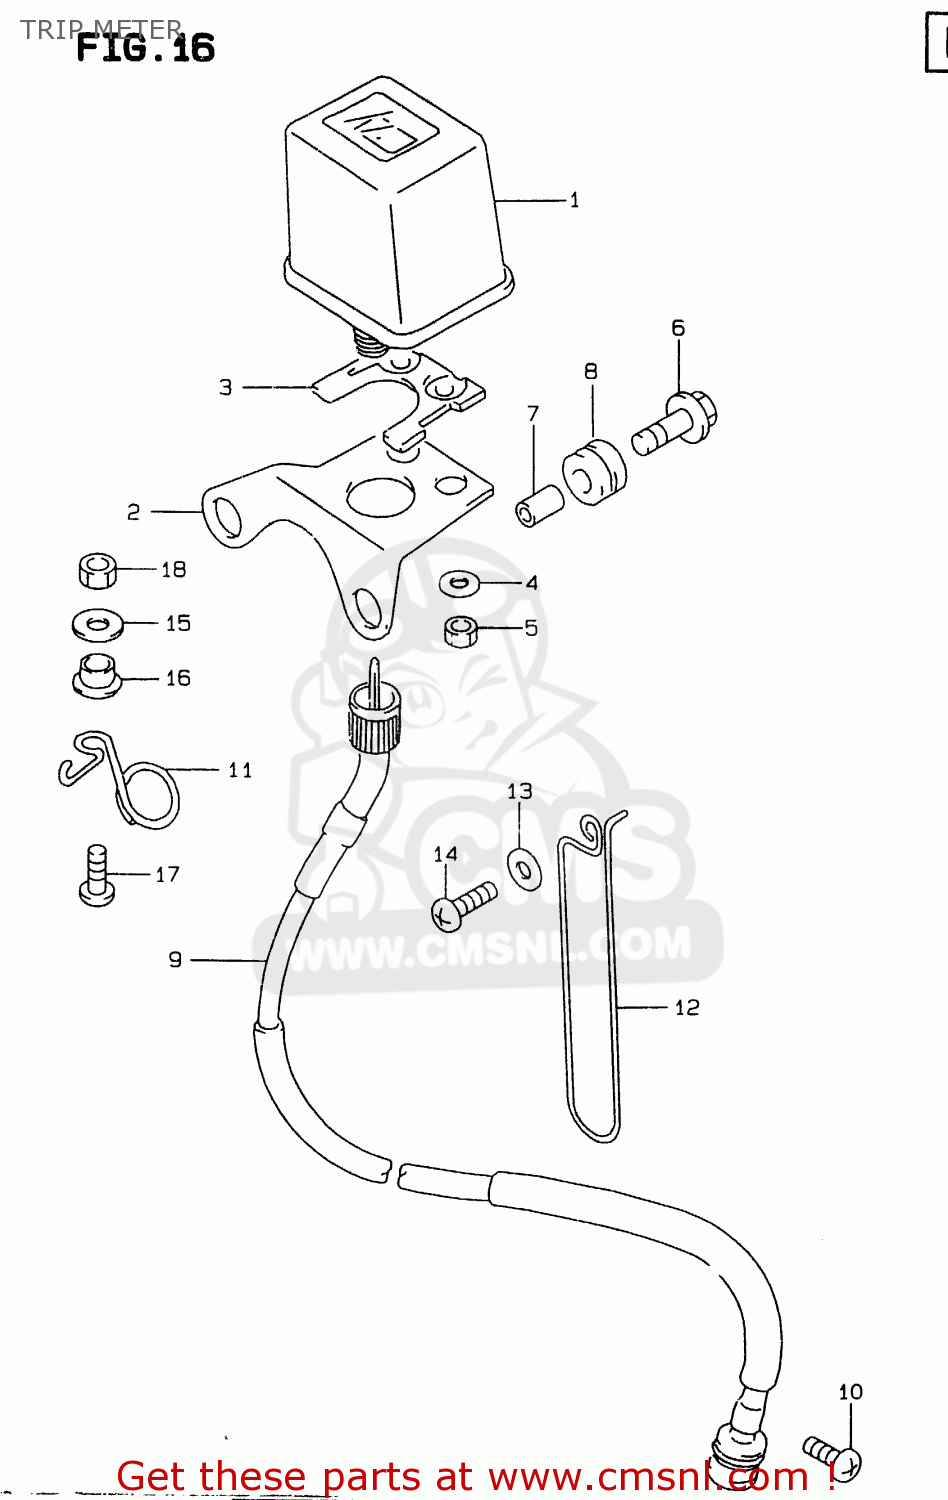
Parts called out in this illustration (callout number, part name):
1	TRIP METER
2	BRACKET
3	CUSHION
4	WASHER (4.3X13X0.80)
5	NUT
6	BOLT(6X25)
7	SPACER(6.1X8X9.5)
8	CUSHION
9	CABLE ASSY,SPEEDOMETER
10	SCREW
11	GUIDE,SPEEDOMETER CABLE
12	GUIDE,METER CABLE NO.2
13	WASHER(6.5X20X1.6)
14	SCREW
15	WASHER
16	WASHER
17	SCREW
18	NUT 6MM
